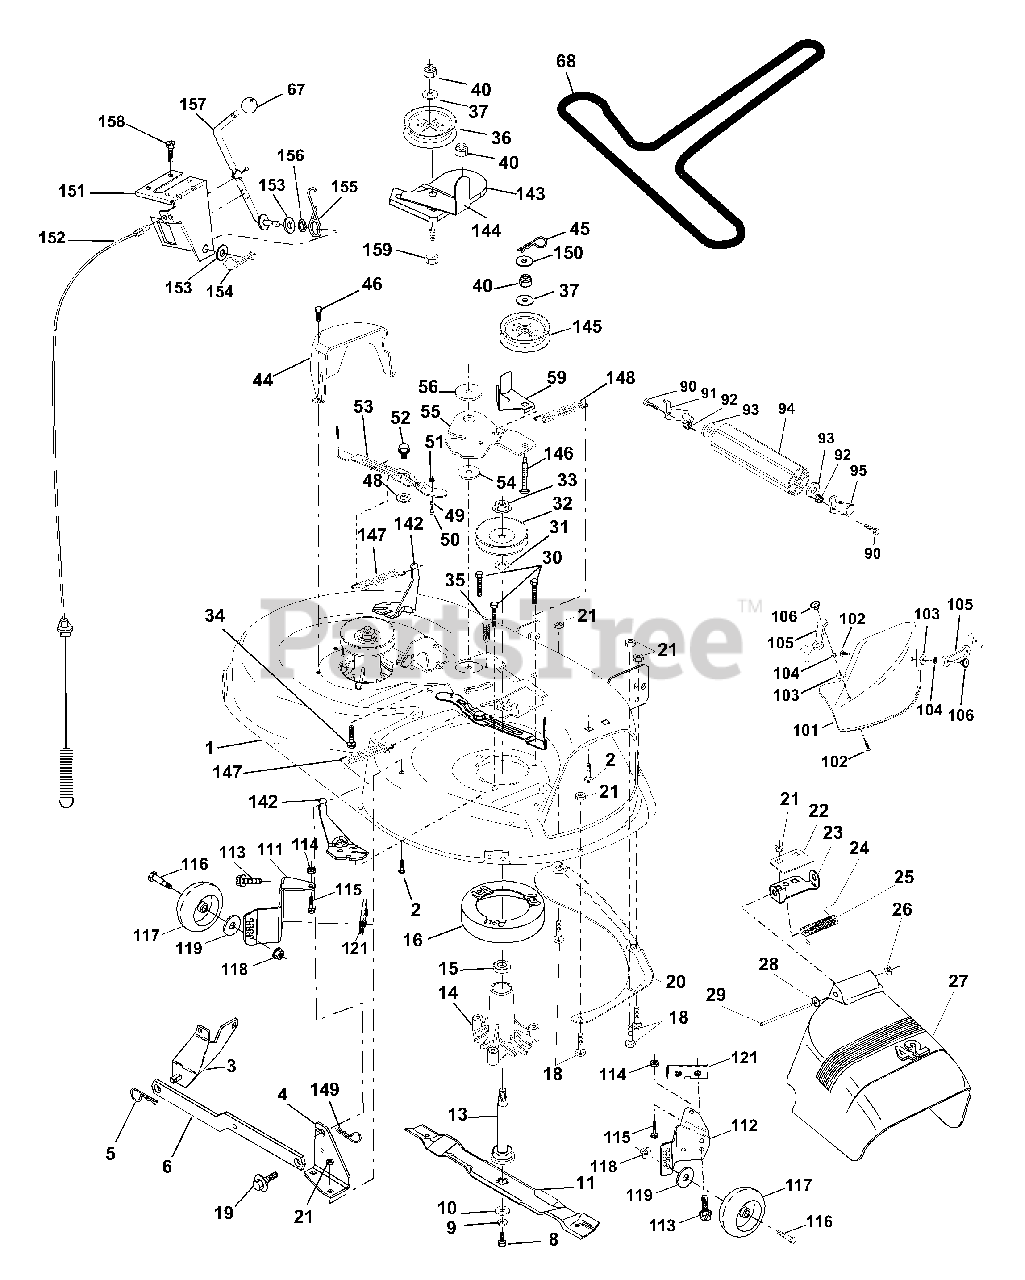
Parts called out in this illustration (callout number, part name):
1	Mower Deck Assembly, 42"
2	Bolt
3	Bracket Asm Fr. Sway Bar 3/42
4	Bracket Asm Deck 42" Sway Bar
5	Retainer Spring
6	Arm, Suspension, Rear
8	Bolt 3/8-24 x 25 Grade 8 patched
9	Washer, Lock
10	Washer,Hardened
11	Blade, Mulching 42" Std
11	Blade Mower 42" Hi-Lift Std
13	Shaft Assembly, Mandrel, Vented
14	Housing, Mandrel, Vented
15	Bearing, Ball, Mandrel
16	Stripper, Mower Deck
18	Bolt, Carriage 5/16-18 x 5/8
19	Bolt, Shoulder
20	Baffle, Vortex
21	Nut
22	Stiffener Bracket
23	Bracket, Deflector Mower 42"
24	Cap, Sleeve 80 x 112 Blk Mower
25	Spring, Torsion, Deflector 2 52
26	Nut, Push Phos & Oil
27	Shield, Deflector 42" Blk
28	Washer 11/32 x 5/8 x 16 Gauge
29	Rod, Hinge 42" 6 75 W/G
30	Screw Thdrol Washer Head
31	Washer, Spacer Mower Vented
32	Pulley, Mandrel
33	Nut, Toplock 9/16
34	Bolt
35	Fastener, Christmas Tree
36	Pulley, Idler, Flat
37	Washer 13/32 x 13/16 x 16 Gauge
40	Nut
44	Guard, Mandrel, LH
45	Retainer
46	Screw, Thdrol 1/4-20 x 5/8 T
48	Washer,Hardened
49	Roller Assembly, Cam Follower
50	Bolt, Shoulder #10-24 Grade 5
51	Locknut
52	Bolt, Shoulder 5/16-18 UNC
53	Arm Assembly, Pad, Brake
54	Washer,Hardened
55	Arm, Idler
56	Spacer, Retainer
59	Guard TUV Idler
67	Knob Round
68	V-Belt, 42" Mower
90	Bolt Fin Hex 3/8-16 Unc x 1
91	Bracket Asm Noseroller LH
92	Nut, Lock, Hex W/Ins 3/8-16 UNC
93	Washer 17/3 x 7/8 x 6 Ga.
94	Roller Nose 38 & 42
95	Bracket Asm Noseroller RH
101	Mulcher Cover
102	Screw
103	Washer, Flat
104	Washer, Lock
105	Latch Assembly
106	Nut, Weld
111	Bracket, Gauge, Wheel LH
112	Bracket, Gauge, Wheel RH
113	Screw 5/16 - 18
114	Nut, Keps 5/16 - 18 UNC
115	Bolt, Carriage 5/16-18 x 1/2
116	Bolt, Shoulder
117	Wheel, Gauge
118	Nut Centerlock 3/8-16
119	Washer 3/8 x 7/8 x 14 Ga.
121	Bracket, Extruded
142	Arm Spring Brake Mower
143	Bracket Arm Idler 42"
144	Keeper Belt
145	Pulley Idler Flat
146	Bolt Carriage Idler
147	Spring Extension
148	Spring Return Idler
149	Retainer Spring Yellow
150	Washer 9/32 x 3/4 x 16 Ga.
151	Bracket Clutch Cable
152	Clutch Cable 42"
153	Washer Flat 3/8" Type B
154	Spring Retainer
155	Spring Retention LVR CLTCH CAB
156	Spacer Clutch Cable
157	Rod Clutch Cable 3/8"
158	Screw Hex Thd Cut 1/4-20 x 5/8
159	Bolt Rdhd Sqn 3/8-16 UNC x 1-3/4
